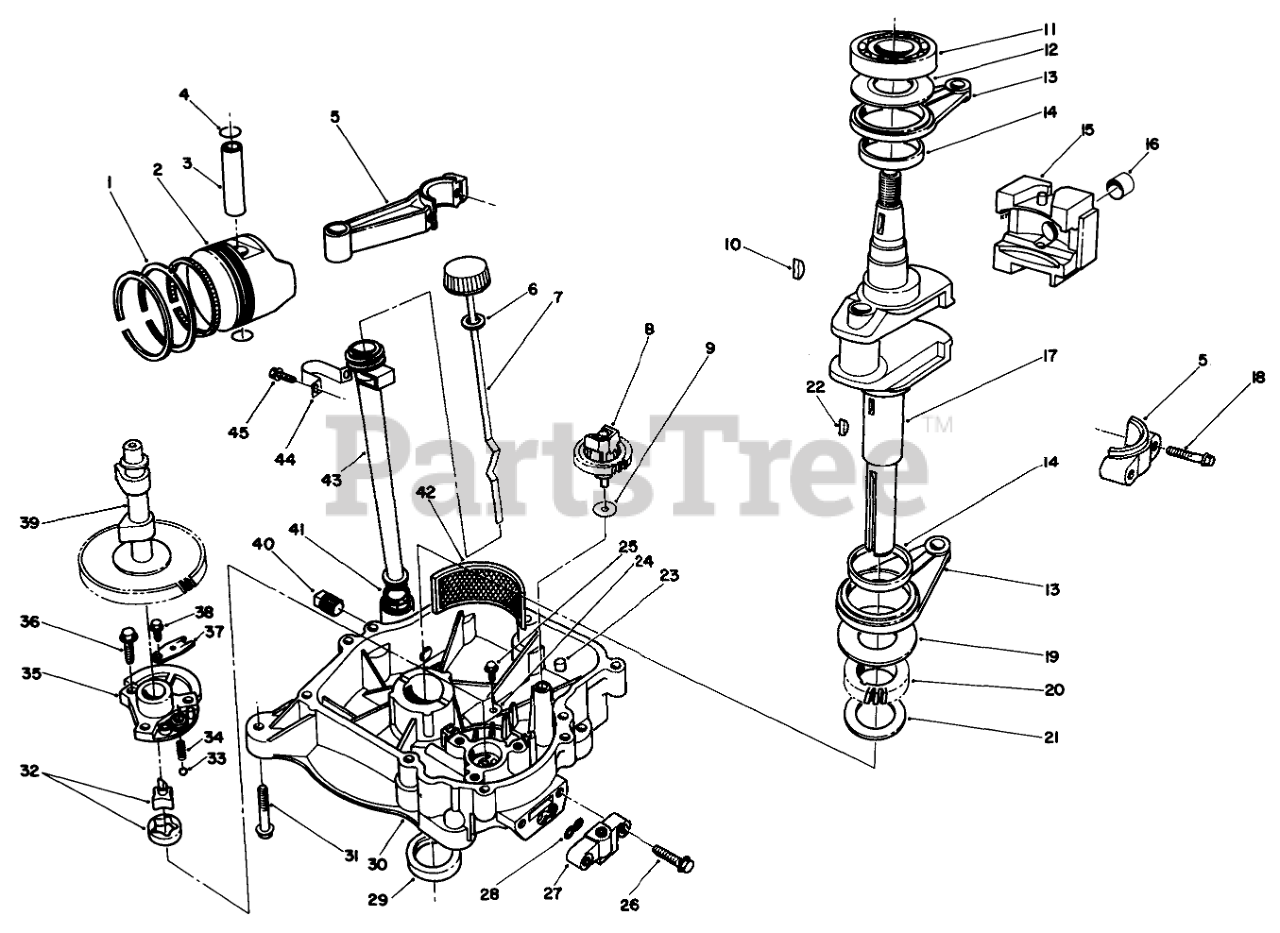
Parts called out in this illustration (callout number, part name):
1	Piston Ring Set
3	Pin-Piston
4	Ring-Snap
5	Rod ASM Incl #10 11
6	Gasket
10	Key-Woodruff
11	Ball Bearing
13	Rod Assembly
14	Bushing
15	Weight
16	Bushing
17	Crankshaft
20	Gear
21	Shim (1.18)
22	Key-Woodruff
23	Pin-Dowel
25	Bolt
26	Bolt
29	Seal-Oil
31	Bolt-Flanged (8X25)
32	Pump ASM-Oil
35	Cover-Pump
36	Bolt-Flanged (8X25)
37	Plate
38	BOLT-FLANGED (6X10)
39	Camshaft
40	Drain Plug
41	O-RING (16mm)
42	Filter-Oil
